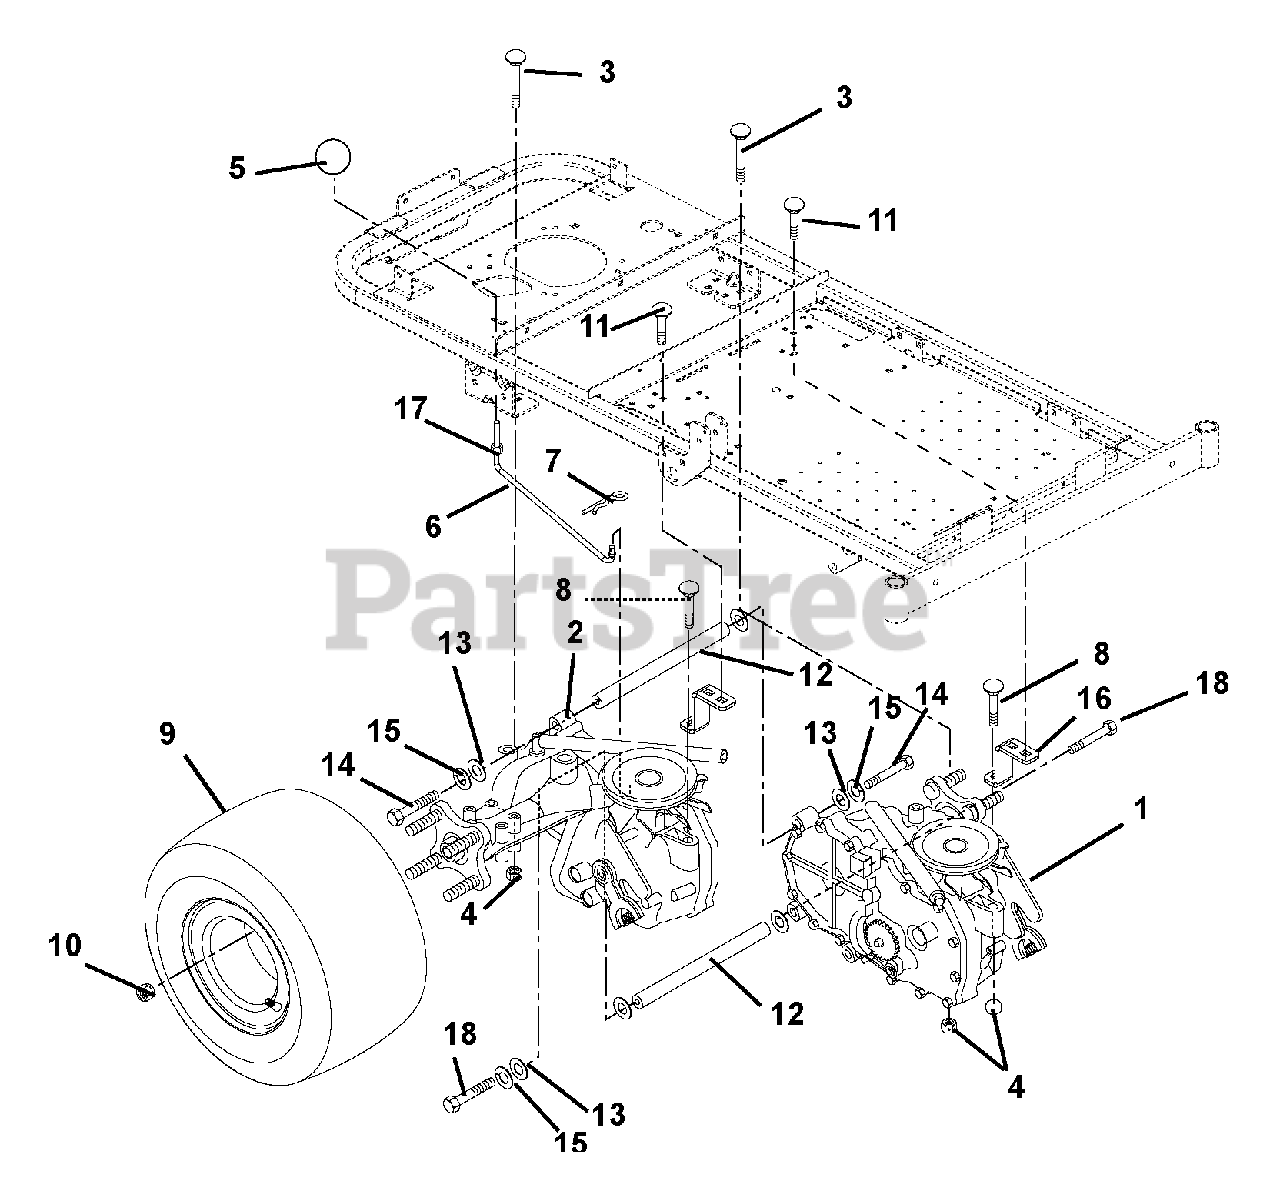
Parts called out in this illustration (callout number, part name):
1	EZT, Left Hand Transaxle-Hydrogear
2	EZT, Right Hand Transaxle-Hydrogear
3	Bolt-Round Head Square Neck .31-18 x 2.75
4	Nut 5/16-18 Flange Nyloc
6	Rod, Dump EZT
7	Pin, Hair
8	Bolt, Round Head Square Neck .31-18 x 2.25
9	Assembly, Tire 8.5 x 18, 2 Ply
10	Nut, Lug .50-20
11	Bolt, Round Head Square Neck .31-18 x 1.00 Grade 5
13	Washer, Flat Steel .344 x .688 x .065
14	Bolt, Hex .31-18 x 2.50 Grade 5
15	Washer, Locking .31 x .078 Regular
16	Strap, Torque
17	Nut-Hex .25-20
18	Bolt-Hex .31-18 x 2.00 Grade 5
